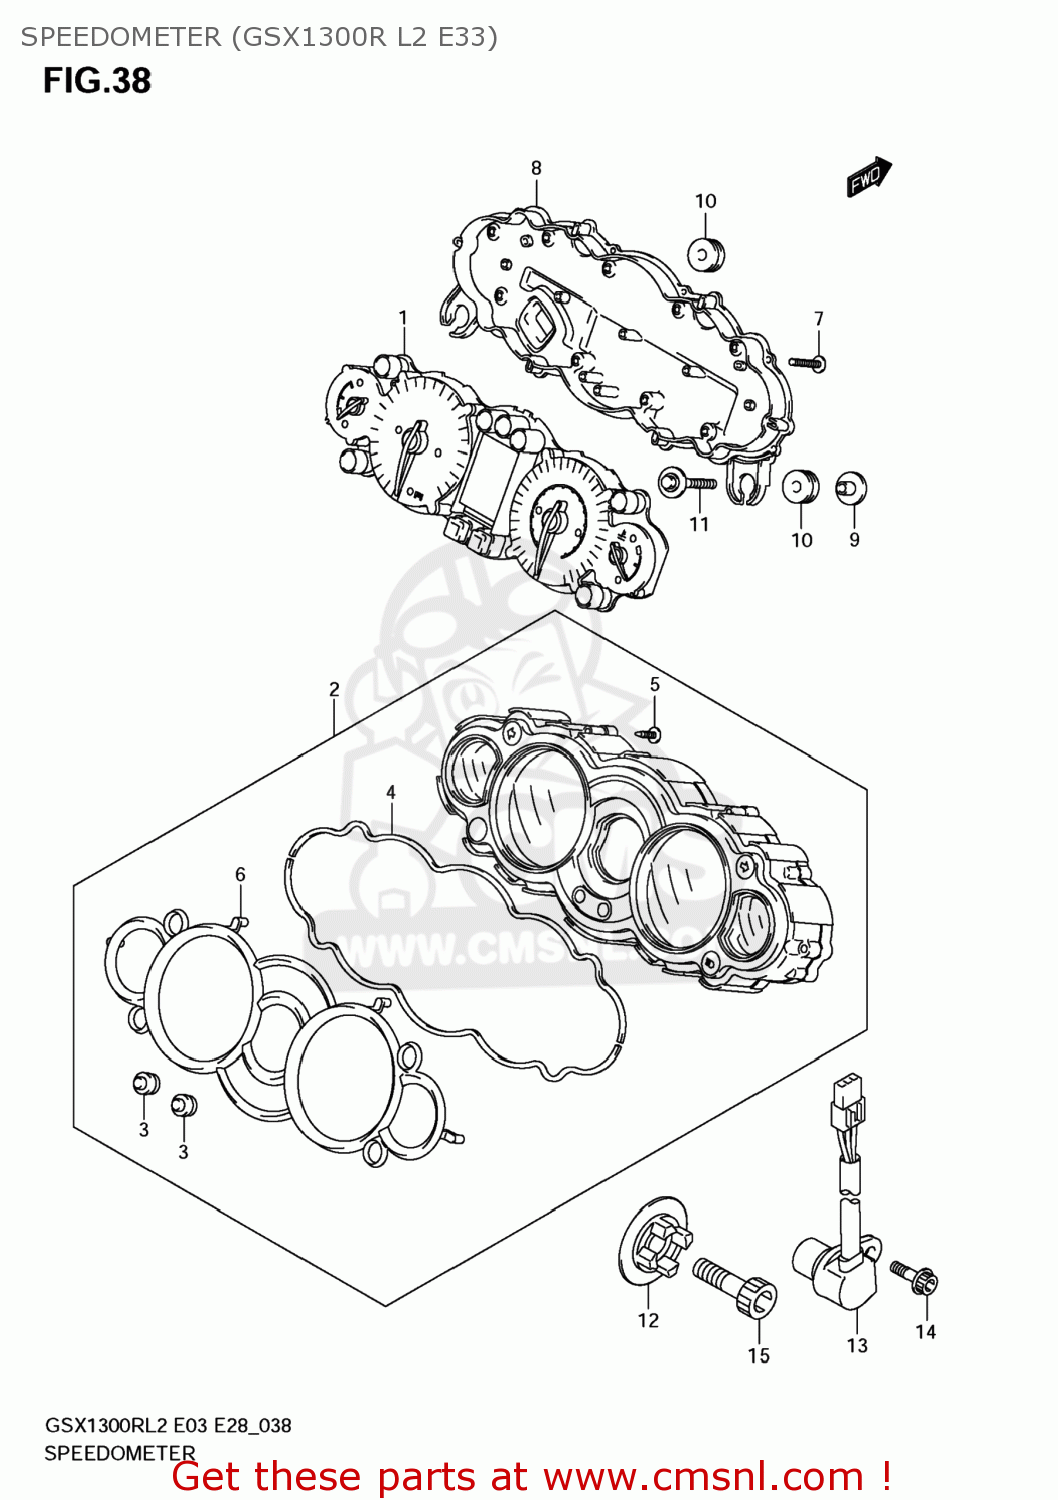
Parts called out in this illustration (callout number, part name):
1	COMBINATION METER
2	UPR CASE
3	RUBBER,SWITCH
4	PACKING (NAS)
5	SCREW(2.3X8)
6	RING
7	SCREW(3X16)
8	LOWER CASE
9	WASHER
10	CUSHION
11	BOLT(6X25)
12	ROTOR,SPEED
13	SENSOR,SPEED
14	BOLT
15	BOLT
